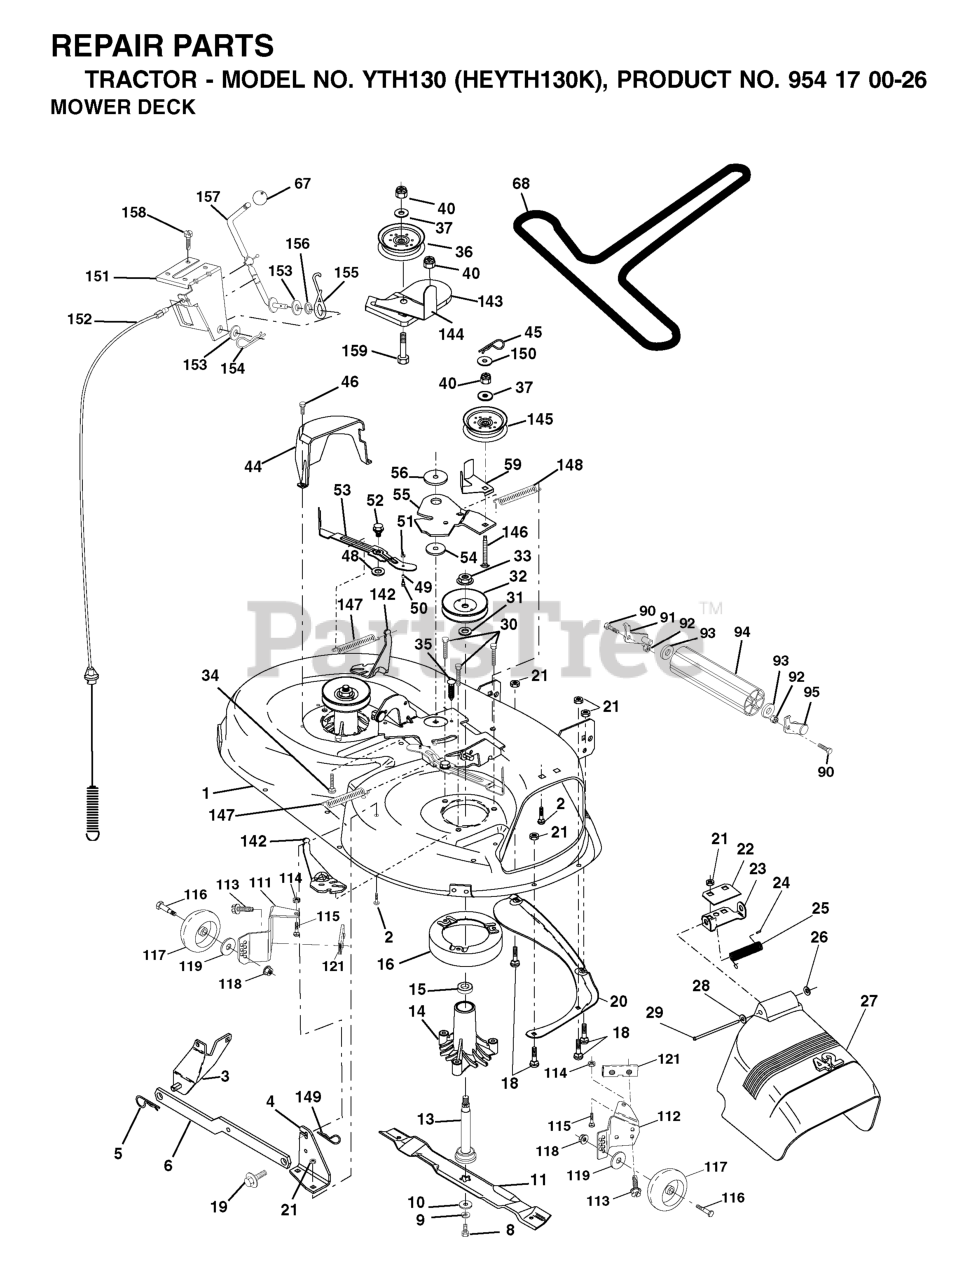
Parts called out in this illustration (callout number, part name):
1	42" DECK KIT
2	RP BOLT 5/16-18 X3/4 ZN/YEL GR
3	BRKT ASM SWAY BAR
4	BRACKET SWAY BAR 42" DECK
5	RETAINER-SPRNG RB
6	REAR SUSP ARM
8	BLADE BOLT
9	LOCKWASHER
10	WASHER.BLADE
11	Blade Mower 42" High Perf.
13	SHAFT ASM VENT
14	HOUSING.MANDREL.VENTED (MACHD)
16	STRIPPER
18	BOLT
19	BOLT SHD 5/16-18
20	BAFFLE.VORTEX
21	LOCKNUT
22	STIFFENER BRACKET
23	DEFLECTOR BRACKET
24	CAP-SLEEVE LT
25	SPRING TORSION
26	NUT PUSH M
27	SHIELD DEFLECTOR
28	Washer 11/32 x 5/8 x 16 Ga SD
29	ROD.HINGE
30	SCREW THDROL ROLLING WASHER HD
31	WASHER
32	PULLEY/MANDREL
33	NUT
35	FASTENER.XMAS.TREE
36	FLAT IDLER PULLEY
37	WASHER
44	GUARD MANDREL LH BLACK
45	RETAINER M
46	SCREW.1/4-20X5/8
49	ROLLER ASM CAM FOLLOWER
52	BOLT.SHOULDER.5/16-18
53	ARM
54	HARDENED WASHER
55	ARM IDLER 42" MOWER LT/YT
56	SPACER.RETAINER.MOWER
59	GUARD, BELT
67	KNOB T (3/8 HOLE)
68	BELT V SECONDARY
90	BOLT
91	BRACKET LH (A)
92	NUT
93	Washer 1 17/32 X 7/8 X 16 Ga
94	NOSE ROLLER
95	BRACKET RH (B)
111	BRACKET WHEEL GAUGE LH 42" DK
112	BRACKET WHEEL GAUGE RH 42" DK
113	Screw Tapping 5/16-18 Unc
114	NUT
115	BOLT.CARR.5/16-18X1/2
116	BOLT M
117	WHEEL.GAUGE.STANDARD
118	LOCKNUT
119	WASHER.5/16.FLAT.STE.STD.
121	BRACKET.EXTRUDED.GAGE.WHEEL
129	WASHER
131	BOLT D
142	ARM SPRING BRAKE MOWER
143	BRACKET, ARM IDLER
144	DNO KEEPER.BELT.42".CLUTCH.CBL
145	PULLEY
146	BOLT, CARRIAGE IDLER BLACK
147	SPRING EXTENSION
148	IDLER RETURN SPRING
149	KIT CYLINDER #70331
151	BRACKET.CLUTCH.CABLE
152	CLUTCH CABLE 42"
153	WASHER FLAT 3/8"
154	SPRING RETAINER
155	SPRING RETENTION LEVER
156	SPACER.CLUTCH.CABLE
157	ROD CLUTCH CABLE 3/8"
158	SCREW LT
